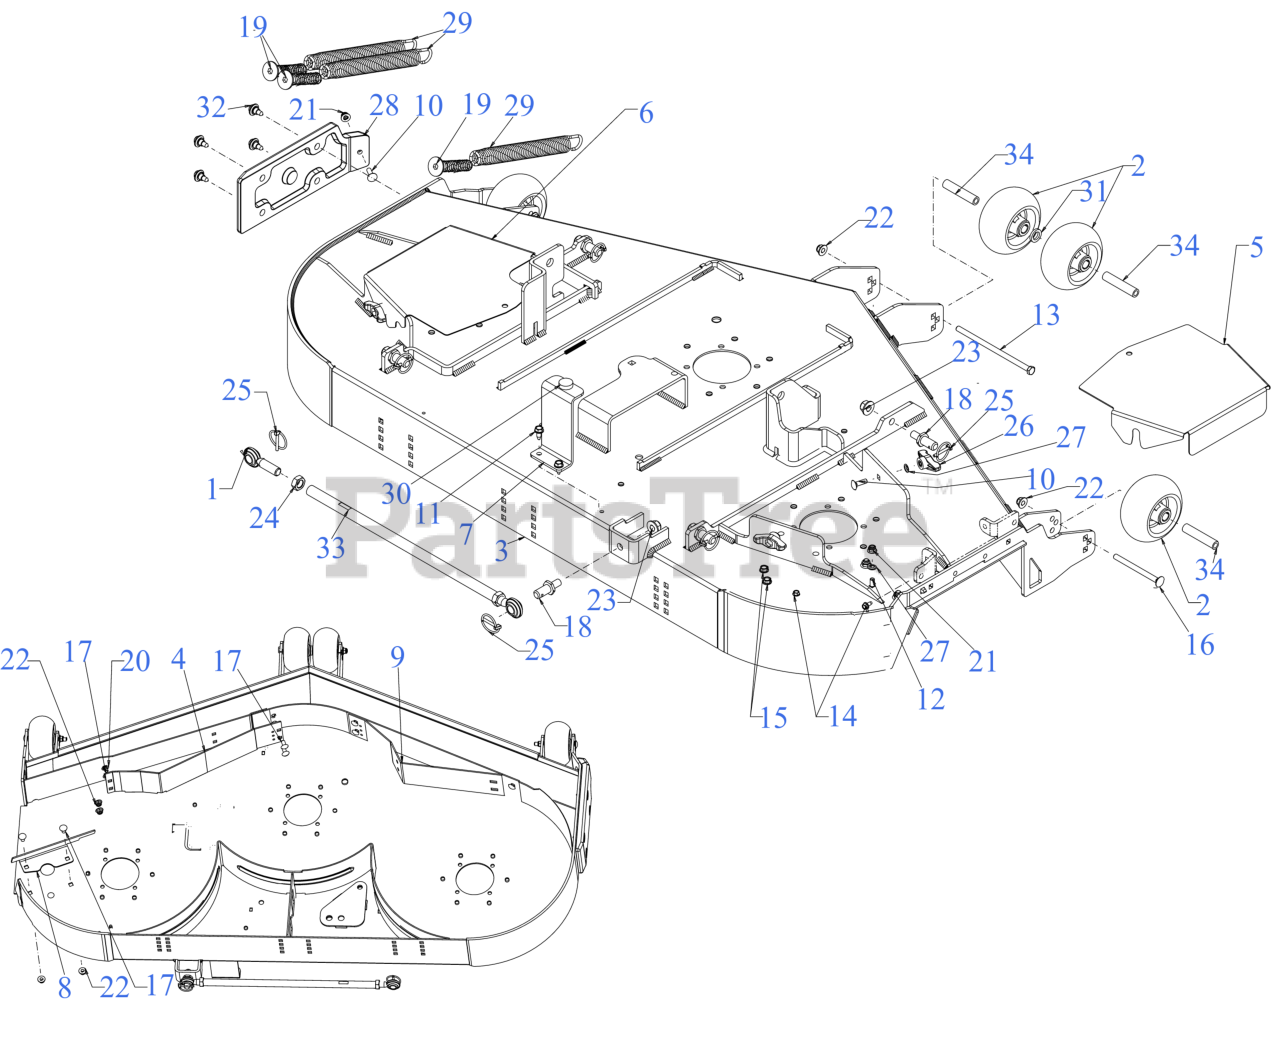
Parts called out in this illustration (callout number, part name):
1	MALE ROD END
2	5" DIA DECK WHEEL COMPLETE
3	60" FAB DECK SHELL
4	DECK BAFFLE
5	BELT COVER (RH)
6	BELT COVER (LH)
7	DECK STOP BRACKET
8	60" DECK CHUTE BAFFLE
9	DECK BAFFLE
10	CARRIAGE BOLT 5/16-18 x 1.00
11	SCREW 5/16-18 x .750
12	CARRIAGE BOLT 5/16-18 x .75
13	SCREW 3/8-16 x 7.25 GR5
14	SCREW 1/4-20 X.500
15	SCREW 5/16-18 x .500
16	CARRIAGE BOLT 3/8-16 x 4.25 GR5
17	CARRIAGE BOLT 3/8-16 x .75
19	SPRING INSERT SCREW
21	FLANGE LOCK NUT 5/16-18
24	HEX JAM NUT 5/8-18
25	LYNCH PIN .1875
26	WING KNOB 5/16-18
28	DECK SKID PLATE (LH)
29	EXTENTION SPRING 1.20 x 11.35
30	RUBBER BUMPER 1.000 x .313
31	FLAT WASHER .632X1.00X.16
32	SHOULDER SCREW .43X.29X5/16-18 TT
33	TUBE .565 X .750 X 18.75"LG
34	WHEEL SPACER .38ID x 3.04LG
